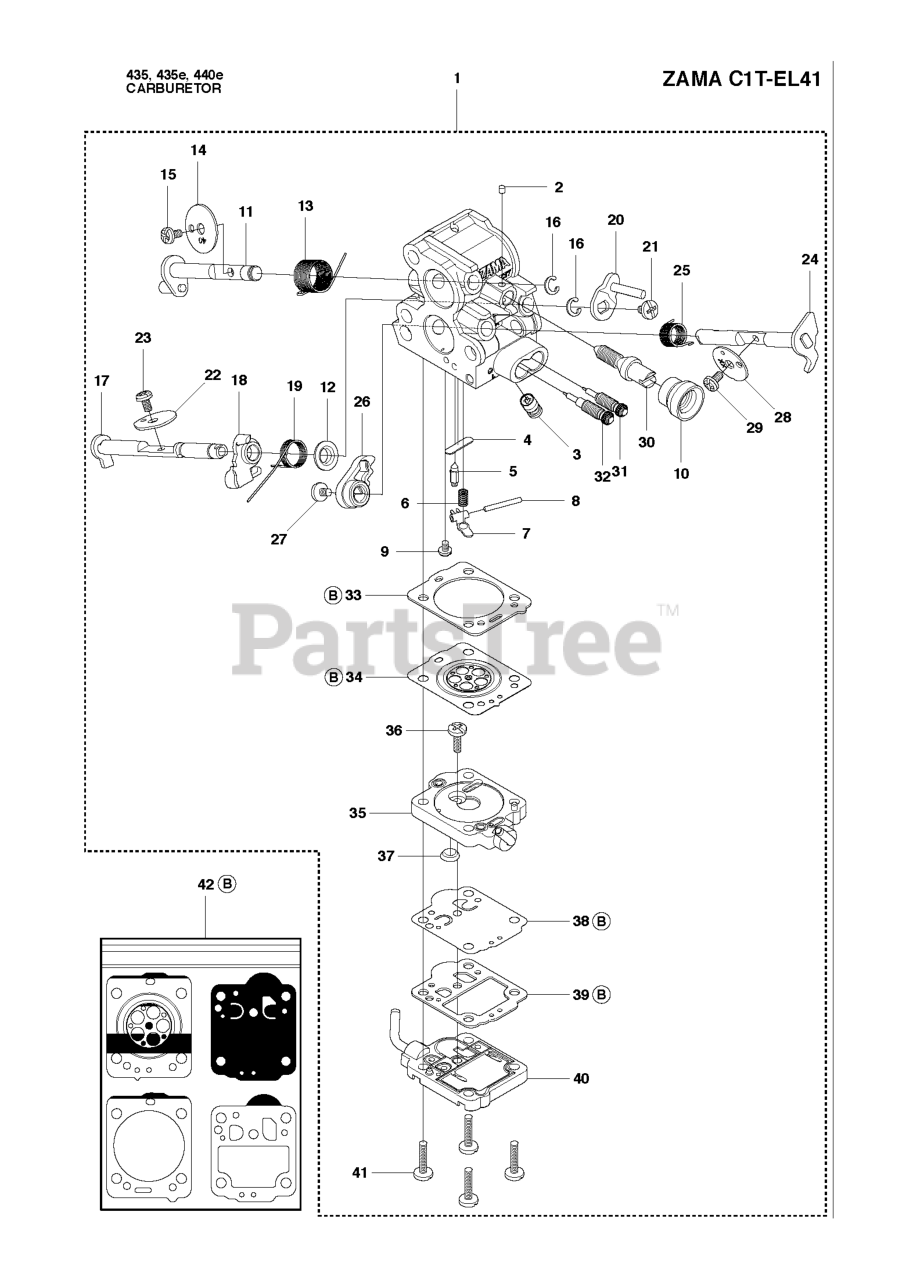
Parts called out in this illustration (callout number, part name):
1	CARBURETOR
3	NOZZLE ASSY
5	INLET NEEDLE
6	SPRING
8	PIN RETAINING SCREW
10	CAP ZAMA 0051034
11	SHAFT ASSY
12	COLLAR ZAMA 005020
17	CHOKE SHAFT ASSY
24	THROTTLE SHAFT ASSY
42	GASKET KIT
